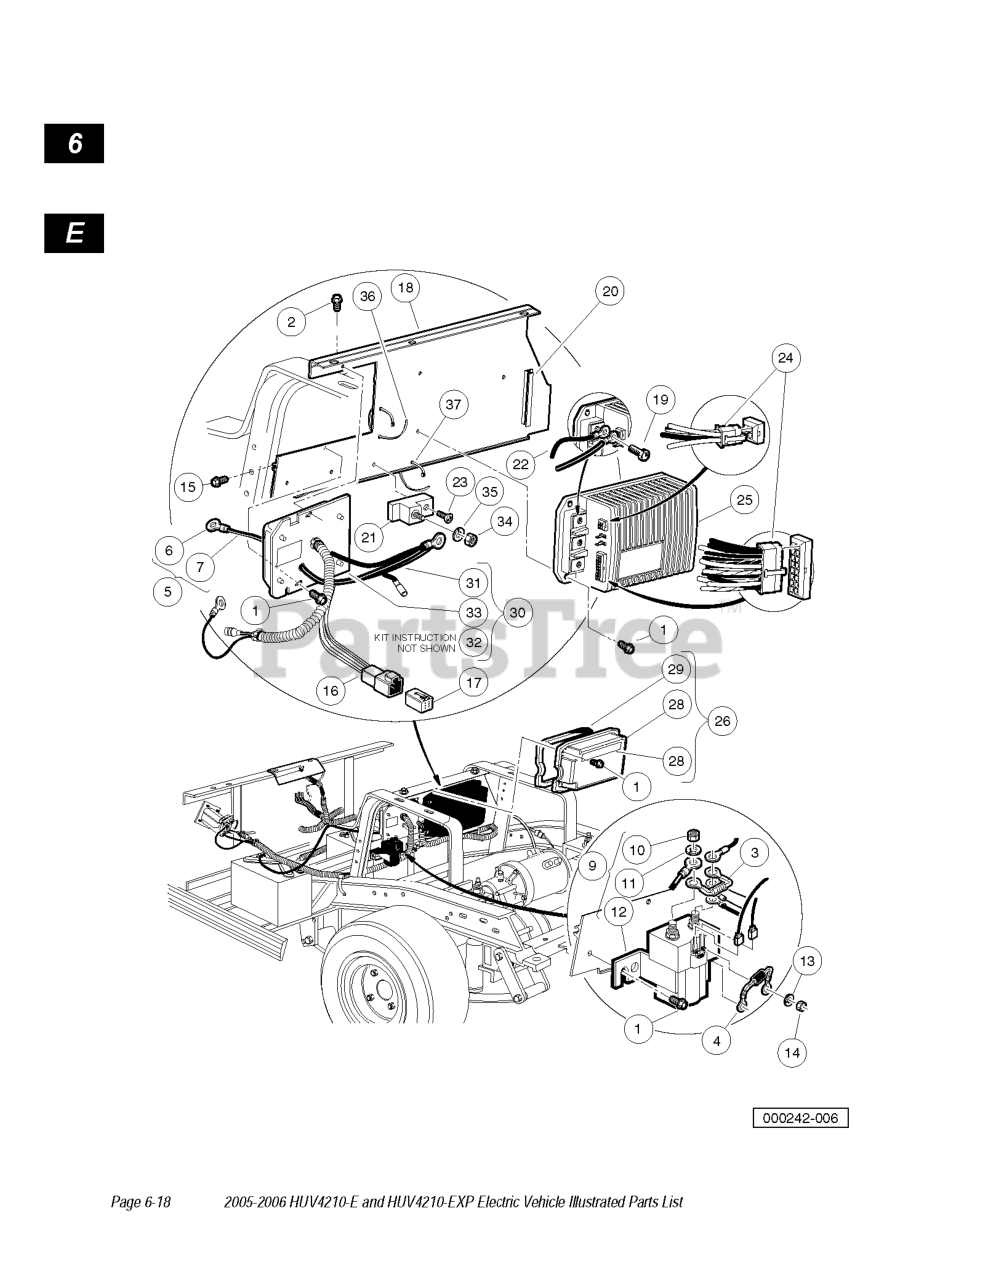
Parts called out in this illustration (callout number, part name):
1	SCREW HX TYP TT
3	RESISTOR ASSEMBLY
4	ASM, DIODE
5	GROUND WIRE KIT 48V
8	TIE WRAP, 8" NYLON
9	SOLENOID, 48V W/ CONTACT STUD
10	NUT, M8-1.25 HEX
15	SCREW, 5/16-18 X 1.25 THRD FRM
16	KIT 6-PINRECEPT AND WEDGE LOCK
17	KIT 6-PIN PLUG AND WEDGE LOCK
18	PLATE, COMPONENT COMMON
19	BOLT IQ CONTROLLER TERMINAL
21	TERMINAL BLOCK
22	WIRE ASSY #10 BLACK
23	SCREW 10-24X.75 PHIL THD-F
24	KIT CONNECTOR IQ CONTROLLER
25	ONTROLLER, 48V IQ GOLF
26	COVER ASM - CONTROLLER
27	DECAL, COMPONENT COVER
28	COVER - CONTROLLER, DEEP
29	GASKET - CONTROLLER COVER
31	Asm Wire #10blk Ground
32	Instr Obc Ds Pre 01-28-2007
34	NUT, 5/16-18 HEX
35	LOCKWASHER, 5/16 SPLIT
36	TIE WRAP , 11" NYLON
37	TIE WRAP, 8" NYLON
